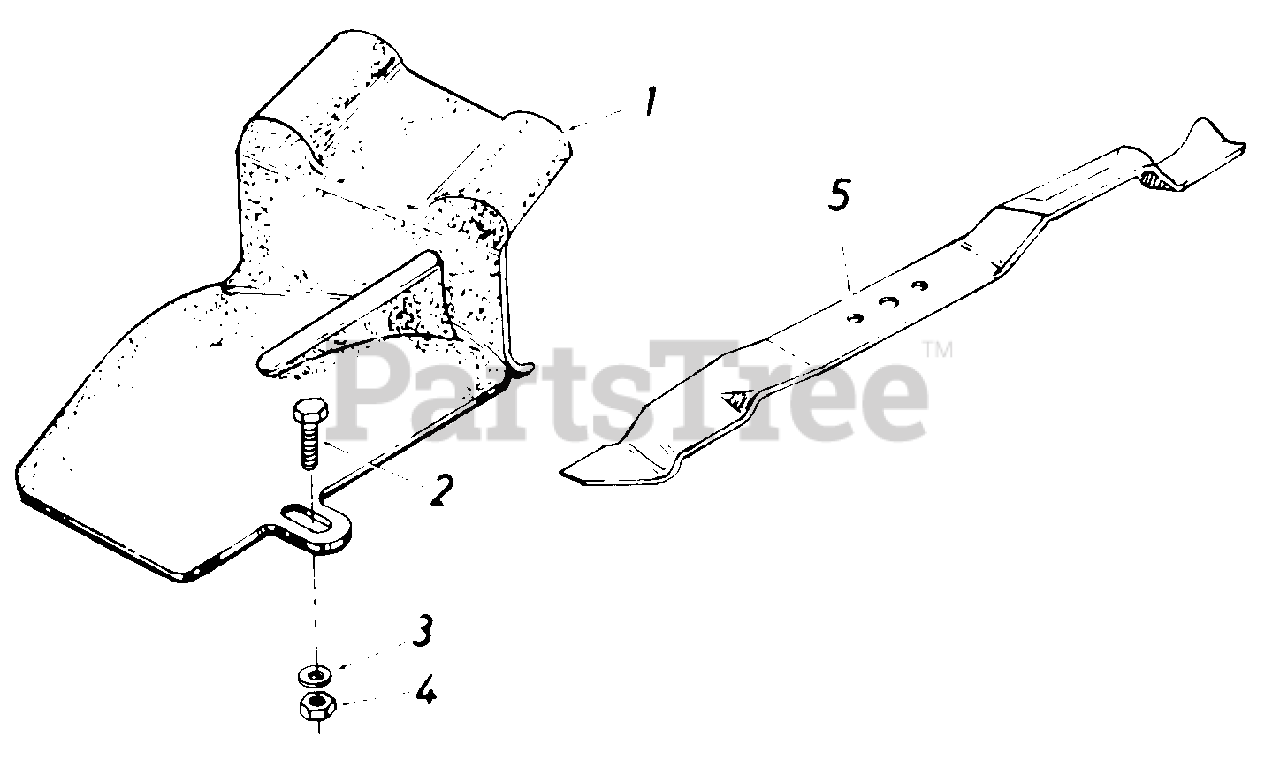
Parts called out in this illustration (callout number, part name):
1	Mulching Baffle
2	Hex Bolt 1/4-20 x .88" Lg.*
3	Belleville Wash. .265 I.D. x .75 O.D. x .093
4	HexJam Nut 1/4-20 Thd.
5	20" Mulching Blade
